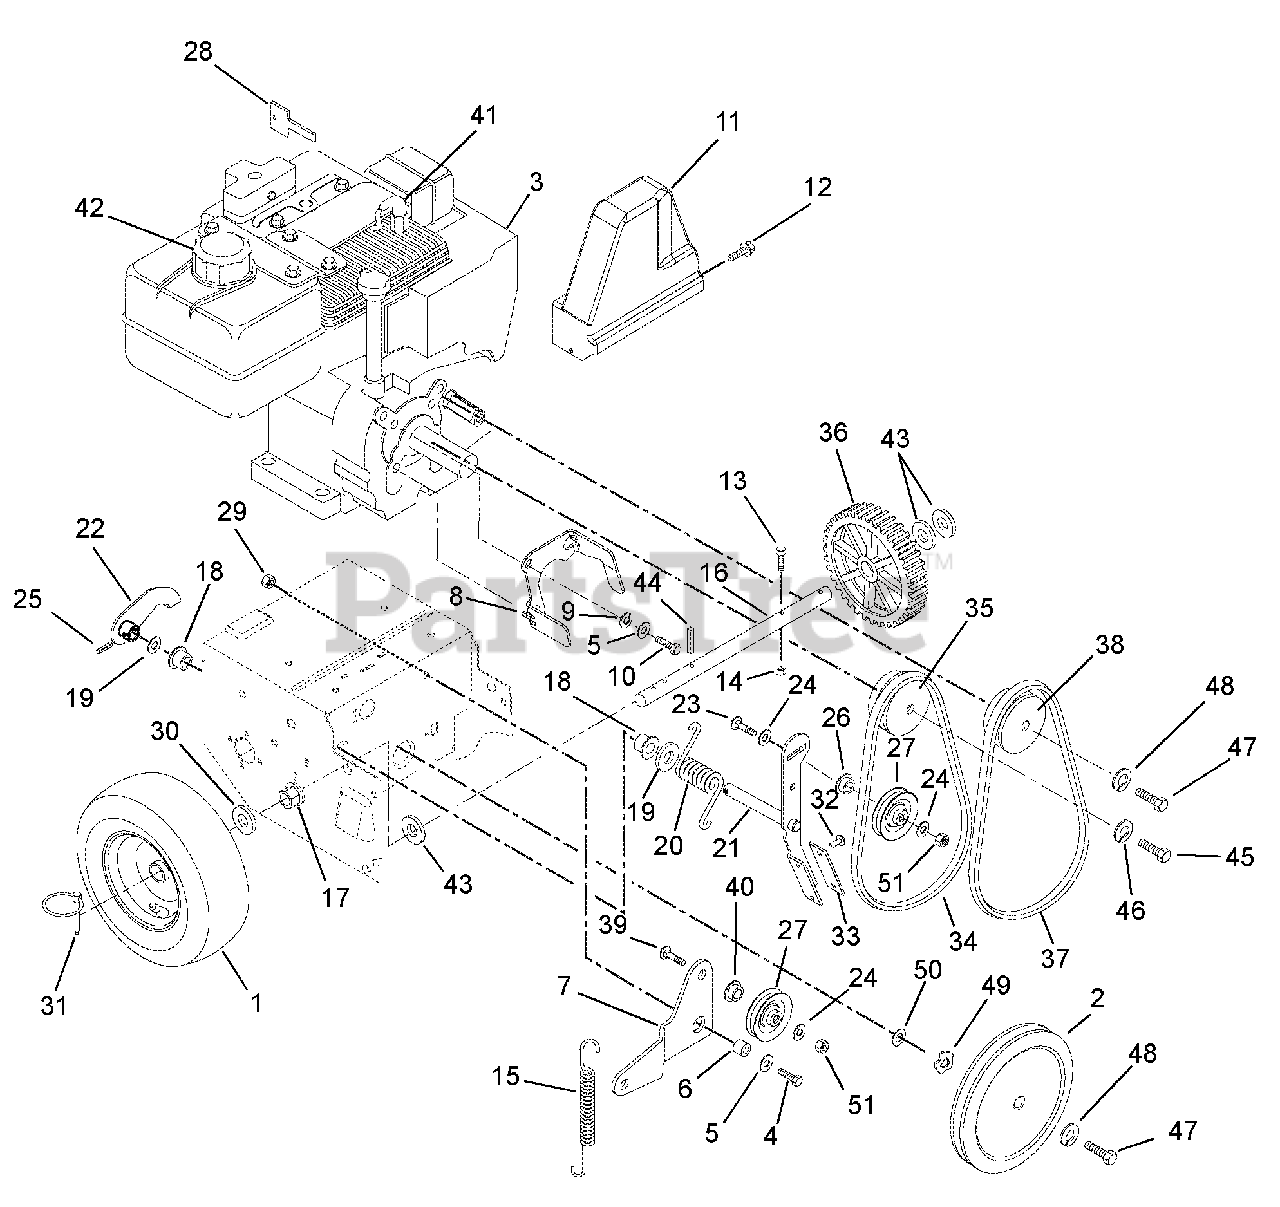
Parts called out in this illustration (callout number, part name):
1	TIRE/WHEEL, LH 13X4.00-6 PIN
1	TIRE/WHEEL, RH 13X4.00-6 PIN
1	TIRE, 2PR X-TRAC TL 13X4.00-6
1	WHEEL, 4.1-6
2	PULLEY, 3L W/HUB, .625 X 8.0
3	ENGINE,5.5HP TECOH195SA RECOIL
4	@BLT-HEX .31-18X.75 GR5 YWZC
5	@WSHR-FL-STL.38X.875X.083 YWZC
6	SPACER BUSHING .5 X .32 X .163
7	IDLER ARM
8	FINGER, BELT
9	WSHR-LK .312X.097 HVY YWZC
10	BLT-HEX .31-24X.75 YWZC GR5
11	BELT COVER
12	@SCR-TAP .25-20X.37 HWH YWZ TR
13	BLT-HEX .25-20X1.75 GR8 YWZC
14	@NUT-LK-CTR .25-20 YWZC
15	SG-TENS .047X.44X3.37 WLD 1.47
16	AXLE SHAFT, COMPACT W/PIN LOCK
17	BSHG-FLG .750X.873HEXX.53X1.18
18	BSHG-FLG .500X.625X.500X.750
19	WSHR-FL-STL .520X.810X.033YWZC
20	SG-TORS .148X1.0X1.53
21	CLUTCH ARM W/BRAKE PAD
22	ARM-CLUTCH
23	@BLT-RHDSHSQNK.31-18X1.25 G5YZ
24	@WSHR-FL-STL.38X.875X.083 YWZC
25	PIN-ROLL .156X.88
26	SPCR, BRG .315X.50X.688X.281
27	IDLER
28	KEY, PUSH/PULL - TECUMSEH
29	@NUT-LK-CTR .31-18 YWZC
30	WSHR-FL-STL.754X1.125X.062YWZC
31	PIN-LOK .31X1.75
32	RVT-TBLR .187X.437 RH ST PL
33	BRAKE LINING
34	BELT,4L TO BE REPLACED07200021
35	SHEAVE, ENGINE
37	V-BELT, 3L-COGGED
38	SHEAVE, CAMSHAFT OH/LH195SA
39	@BLT-RHDSSQNK .31-18X1.00 G5YZ
40	BSHG, FLG .325X.499X.26X.88
41	PLUG, SPARK
42	CAP, FUEL - TECUMSEH
43	WSHR-FL-STL .755X1.25X.125 YZ
44	PIN-ROLL .188X1.25
45	BLT-HEX .38-24X1.0 YWZC GR5
46	@WSHR-LK .38X.094 REG YWZC
47	BLT-HEX .25-28X.75 GR5 YWZC
48	WSHR-LK .250X.077 HVY YWZC
49	WSHR-WAVE .69X.84X.011
50	WSHR-THRST .625 X 1.0 X .03
51	@NUT-LK-CTR-JAM .31-18 YWZC
